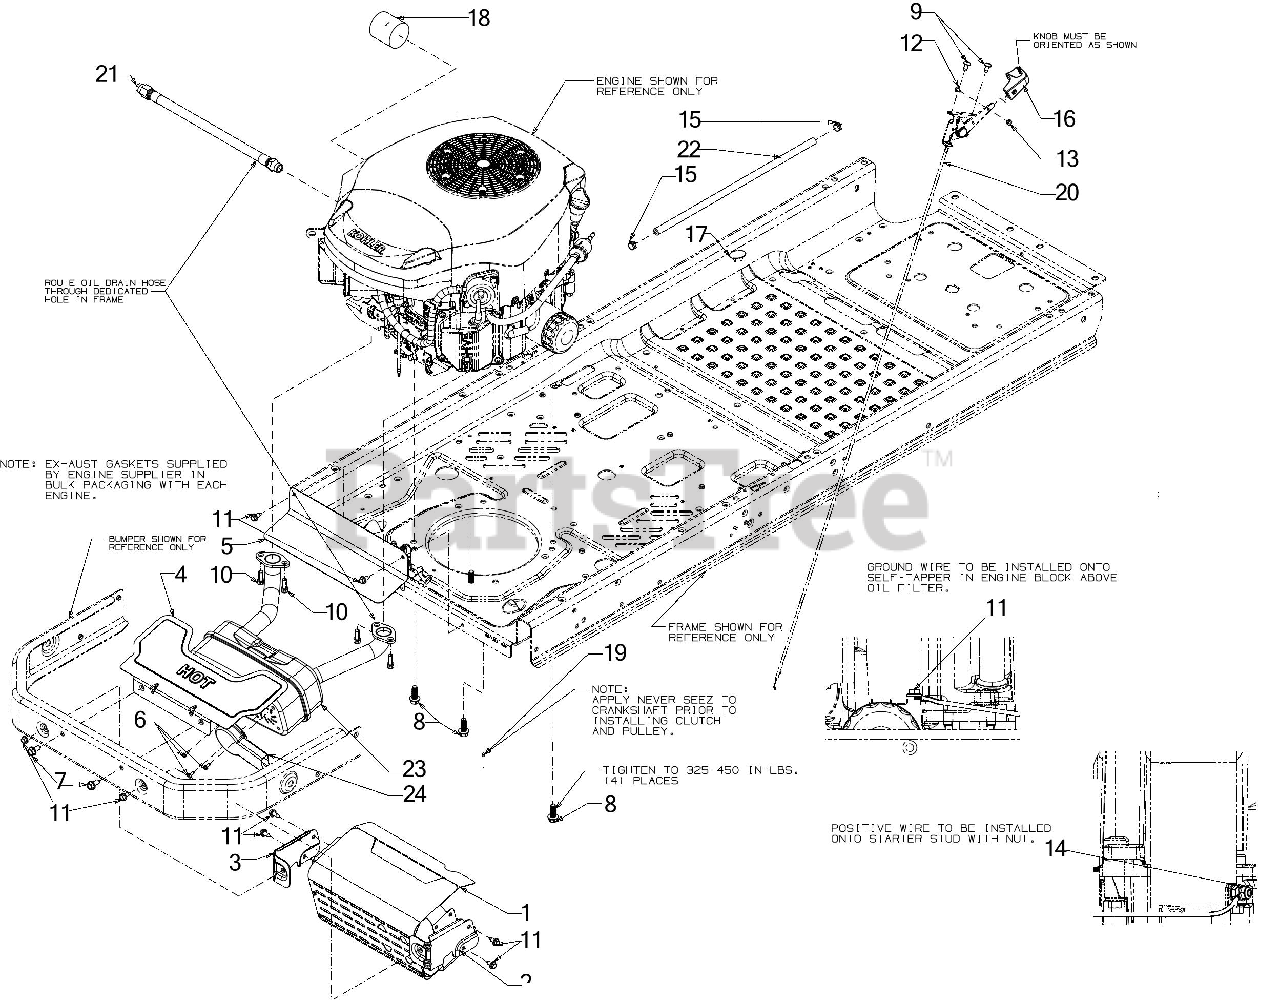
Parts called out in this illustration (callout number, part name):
1	MUFFLER SHIELD W/EXTENSION
2	MUFFLER SHIELD BRACKET (RH)
3	MUFFLER SHIELD BRACKET (LH)
4	MUFFLER HEAT SHIELD
5	LOWER HEAT SHIELD
6	HEX SCREW WASHER HD #8-18 x 0.500
7	SCREW 5/16-18 x .750
8	SCREW 3/8-16 x 1
9	SCREW 1/4-20 x .5
10	SCREW 5/16-18 x .625
11	SCREW 1/4-20X.625
12	SCREW #8-32X.38 LG
13	HEX NUT 8-32
14	FLANGE LOCK NUT
15	HOSE CLAMP 1/20
16	THROTTLE CONTROL KNOB
17	CHOKE PLUG
18	SAE OIL 10W30
19	ANTI-SIEZE GREASE
20	THROTTLE CABLE 38"
21	OIL DRAIN HOSE
22	FUEL HOSE LOW PERMEATION
23	EXHAUST MUFFLER
24	EXHAUST DELECTOR
